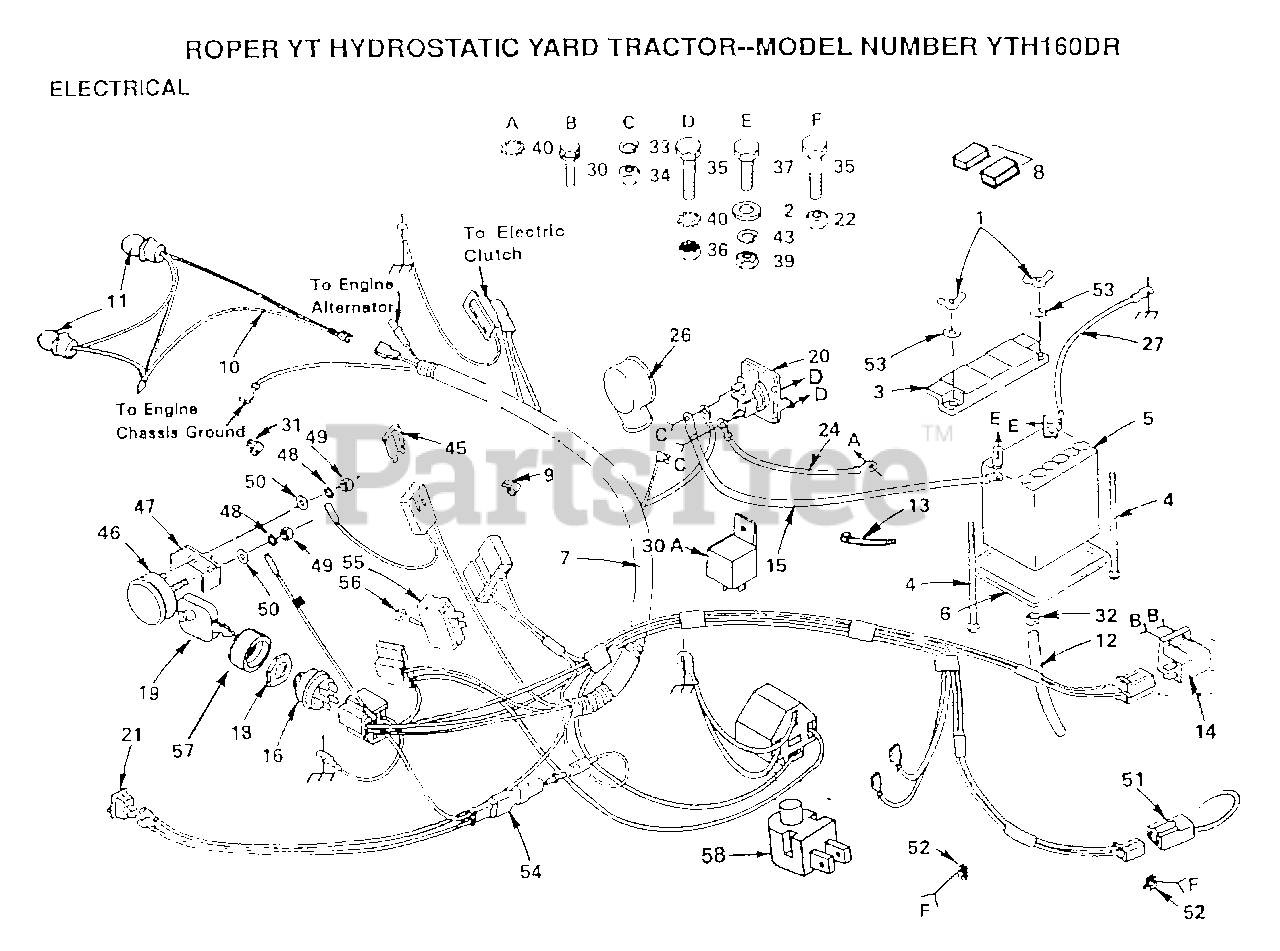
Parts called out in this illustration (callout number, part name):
2	WASHER
4	BOLT
6	"TRAY T, BATTERY"
8	"CAP,BATTERY "
10	HARNESS T
13	WIRE TIE
14	SWITCH-INTER. GT
15	CABLE-BATTERY T
21	SWITCH LT
24	"CABLE T, BATTERY"
27	CABLE T
30	SCREW
30A	RELAY ASSY T
31	CLIP T
32	"SCREW, TAPPING LT"
34	NUT
35	BOLT
36	NUT
37	BOLT LT
43	LOCKWASHER
45	FUSE HYT
46	AMMETER T
50	WASHER
52	CLIPT
53	LOCKWASHER GT
55	SWITCH.PTO.T
56	HEX NUT T
58	SWITCH SEAT
60	"NUT,KEPS"
